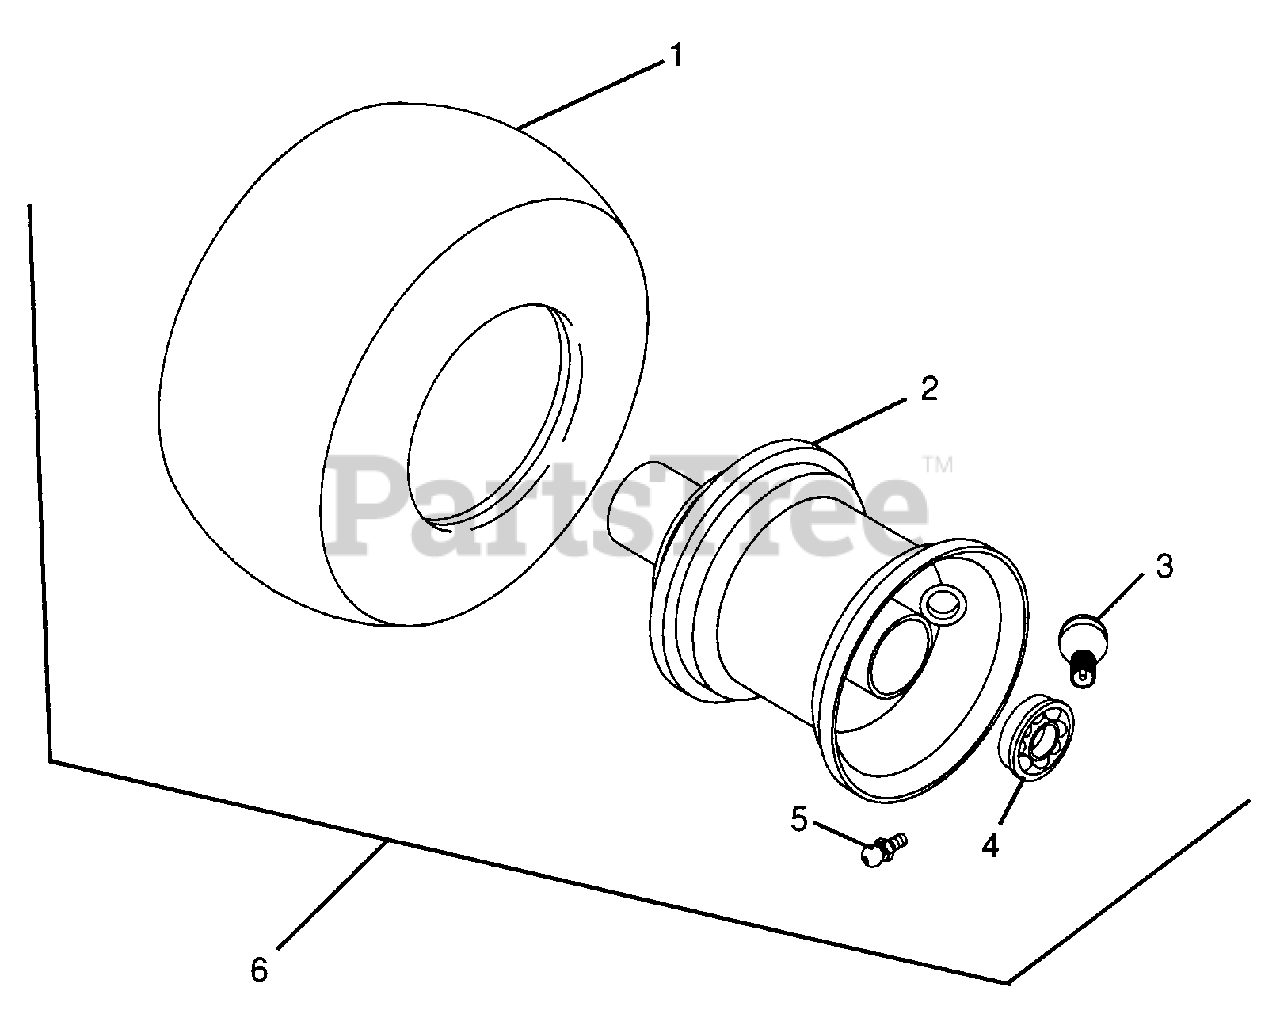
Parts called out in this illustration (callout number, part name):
1	Tire 13 x 6.50-6
2	Rim-Assembly 4.5 x 3.75
3	Valve Stem Assembly
4	Radial Bearing
5	Fitting-Lube .25-28 x .256
6	Assembly, Wheel, 13 x 6.50-6
